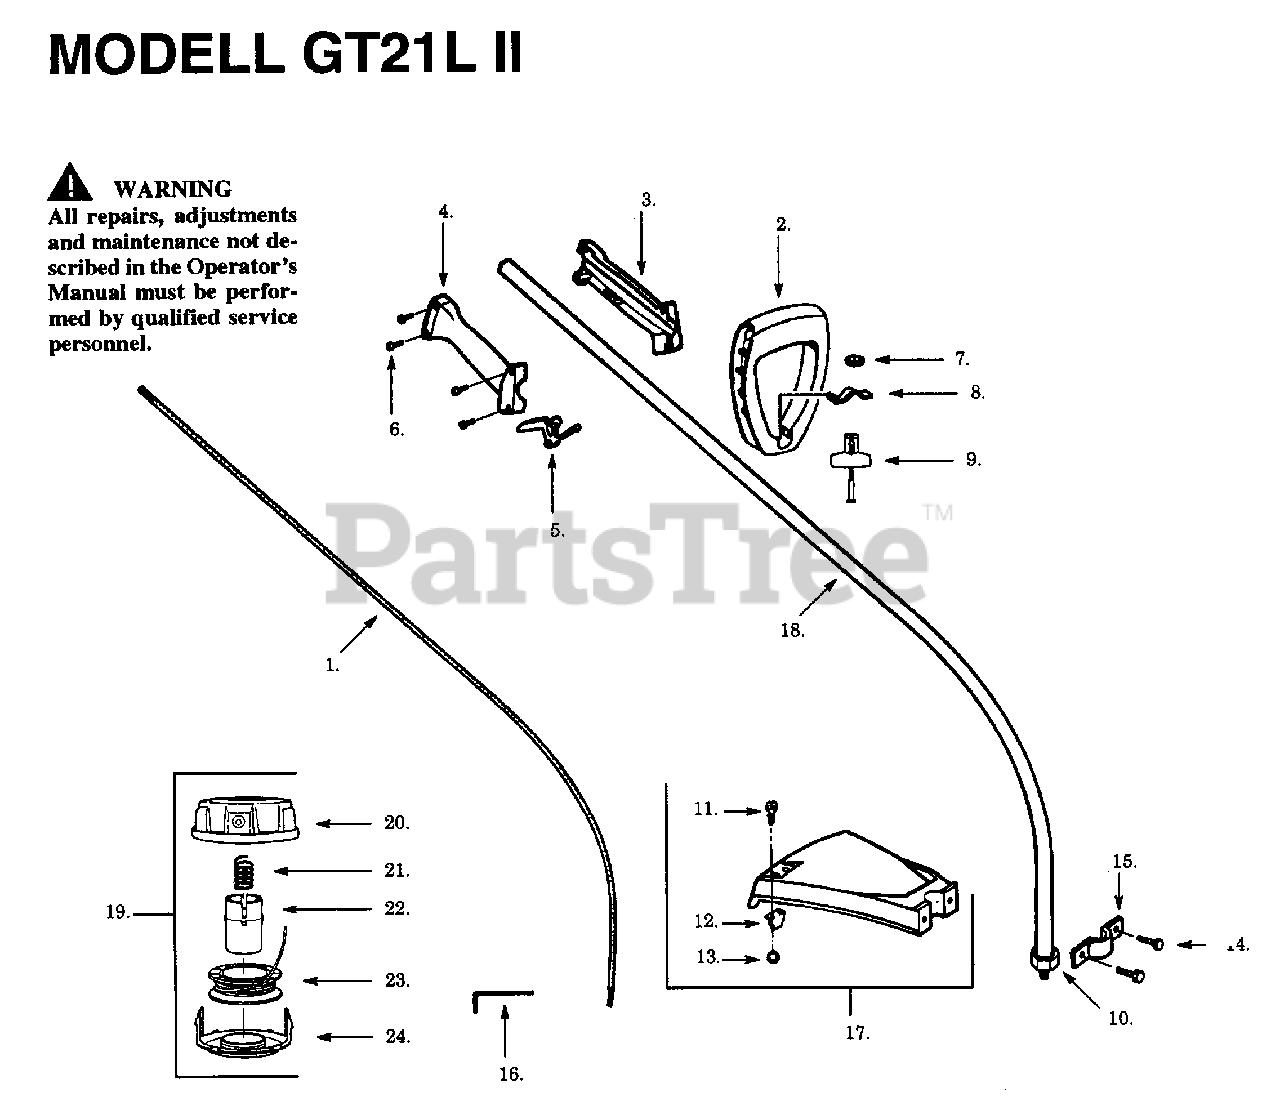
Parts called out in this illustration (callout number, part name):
1	SHAFT-FLEX (48")
2	REPL BY 530 06 94-96
3	THROTTLE HOUSING LEFT
4	THROTTLE HOUSING RIGHT
5	THROTTLE LEVER
6	SCREW - THROTTLE HOUSING
7	NUT (1/4-20)
8	CLAMP-ASSIST HANDLE
9	KIT "T" HANDLE
12	LIMITER-LINE
13	LOCKNUT-(10-24)
14	SCREW-1/4-10X1-1/8 HEX
15	BRACKET-SHIELD
16	ALLEN KEY
17	KIT-SHIELD (SERVICE) BLACK
18	REPL BY 530 09 48-91
19	CUTTING HEAD ASSEMBLY
20	HUB AND SHAFT ASSY
23	SPOOL W/ LINE NLA
